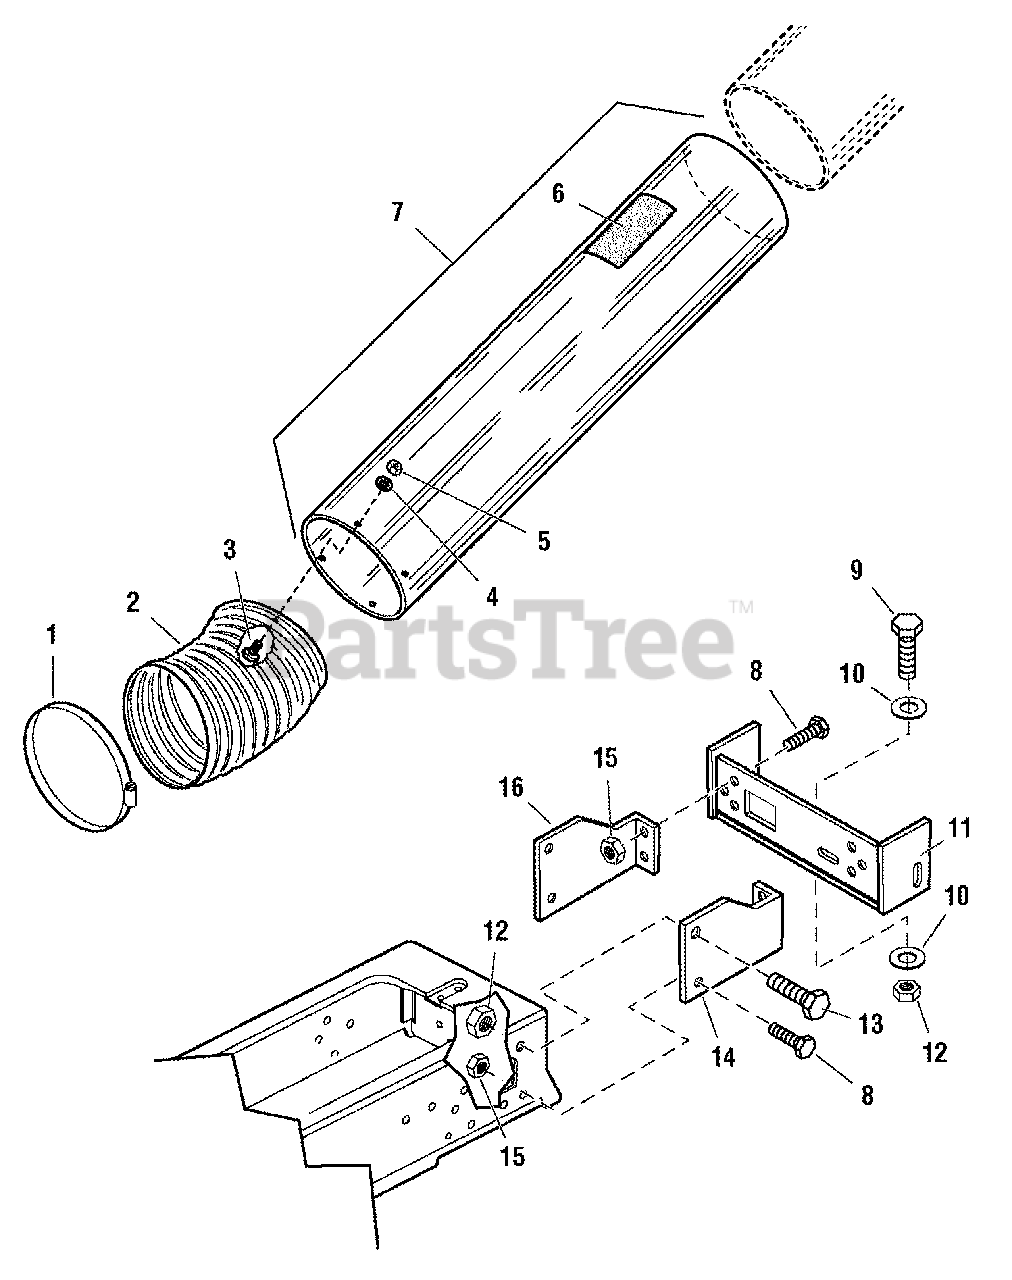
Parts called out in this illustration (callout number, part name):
1	CLAMP, Hose 6", Band Type
2	HOSE, Vac Col, 6 x 12
3	SCREW, Truss Head, Phillips, #10-32 x 1/2
4	WASHER, #10-32
5	NUT, Hex Washer, #10-32
6	DECAL, Cleaning Instructions
7	TUBE & DECAL ASSEMBLY (Includes Ref. No.6)
8	CAPSCREW, Hex Head, 3/8-16 x 1
9	CAPSCREW, Hex Head, 1/2-13 x 1-1/4
10	WASHER, 1/2
11	HITCH, Cart
12	NUT, Hex Centerlock, 1/2/2013
13	CAPSCREW, Hex Head, 1/2-13 x 1
14	ADAPTER, Hitch RH
15	NUT, Hex Centerlock, 3/8-16
16	ADAPTER, Hitch LH
